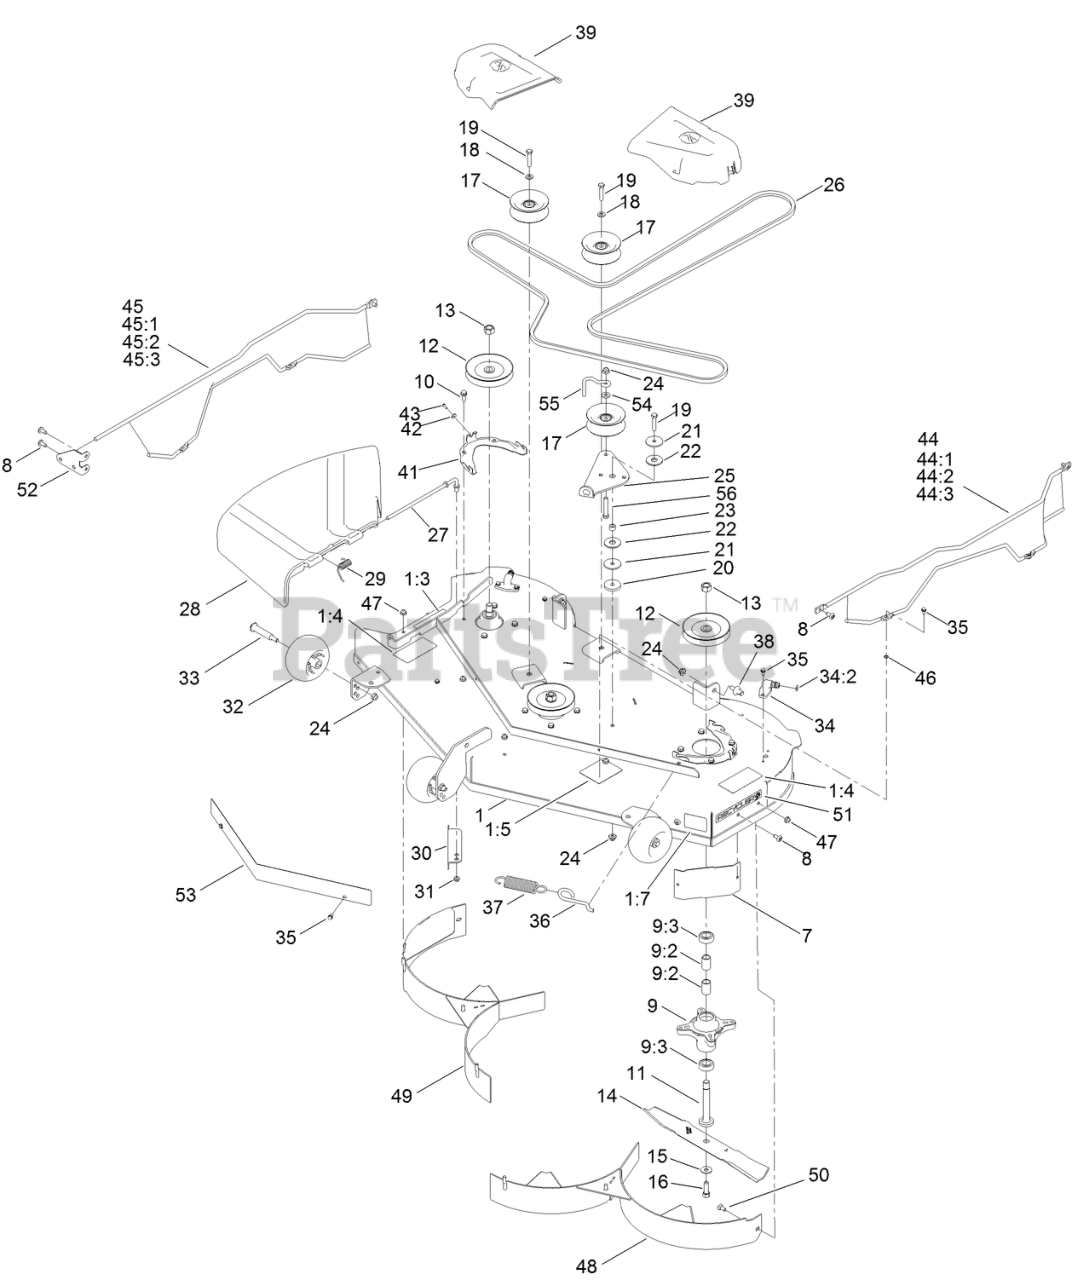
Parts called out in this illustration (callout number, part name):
1	50 INCH DECK AND DECAL ASM
1:3	DECAL-DANGER
1:4	DECAL-DANGER, DECK
1:5	DECAL-ROUTING, BELT
1:7	DECAL-SCALP, ANTI
7	BAFFLE-CORNER
9	SPINDLE ASM
9:2	SPACER
9:3	BEARING-BALL
10	SCREW-TAPTITE
11	SHAFT-SPINDLE
12	PULLEY
13	Nut-Hex
14	BLADE-MULCH, 17.50 INCH
15	WASHER-BELLEVILLE
16	SCREW-HH
17	PULLEY-IDLER, FLAT
18	WASHER-FLAT
19	SCREW-HH
20	WASHER-PLAIN
21	Washer
22	WASHER-FRICTION, COMPOSITE
23	SPACER
24	NUT-HF, NI
25	ARM-IDLER
26	V-BELT
27	ROD-PIVOT
28	DEFLECTOR-DISCHARGE
29	SPRING-TORSION
30	BAFFLE-CUTOFF
31	NUT-HEX
32	ROLLER-SCALP, ANTI
33	BOLT-SHOULDER
34	FITTING-WASHOUT
34:2	O-RING
35	SCREW-HWH
36	HOOK-RETURN SPRING
37	SPRING-EXTENSION
38	PIN-DECK
39	COVER-BELT
41	BRACKET-COVER, BELT
42	WASHER-PLAIN
43	SCREW
44	LEFT GUARD ASM
44:2	ROD-TOP, LEFT
44:3	ROD-SUPPORT, LOWER
45	RIGHT GUARD ASM
45:2	ROD-TOP, RIGHT
45:3	ROD-SUPPORT, LOWER
46	NUT-RETAINING
47	NUT-HF
48	50IN BAFFLE ASM
49	50IN BAFFLE ASM
50	BOLT-CARR
51	DECAL-RECYCLER
52	PLATE-MOUNT, GUARD
53	SHIELD-FRONT
54	SPACER-HUB, BLOWER
55	BELT GUIDE - IDLER
56	SCREW-HH
